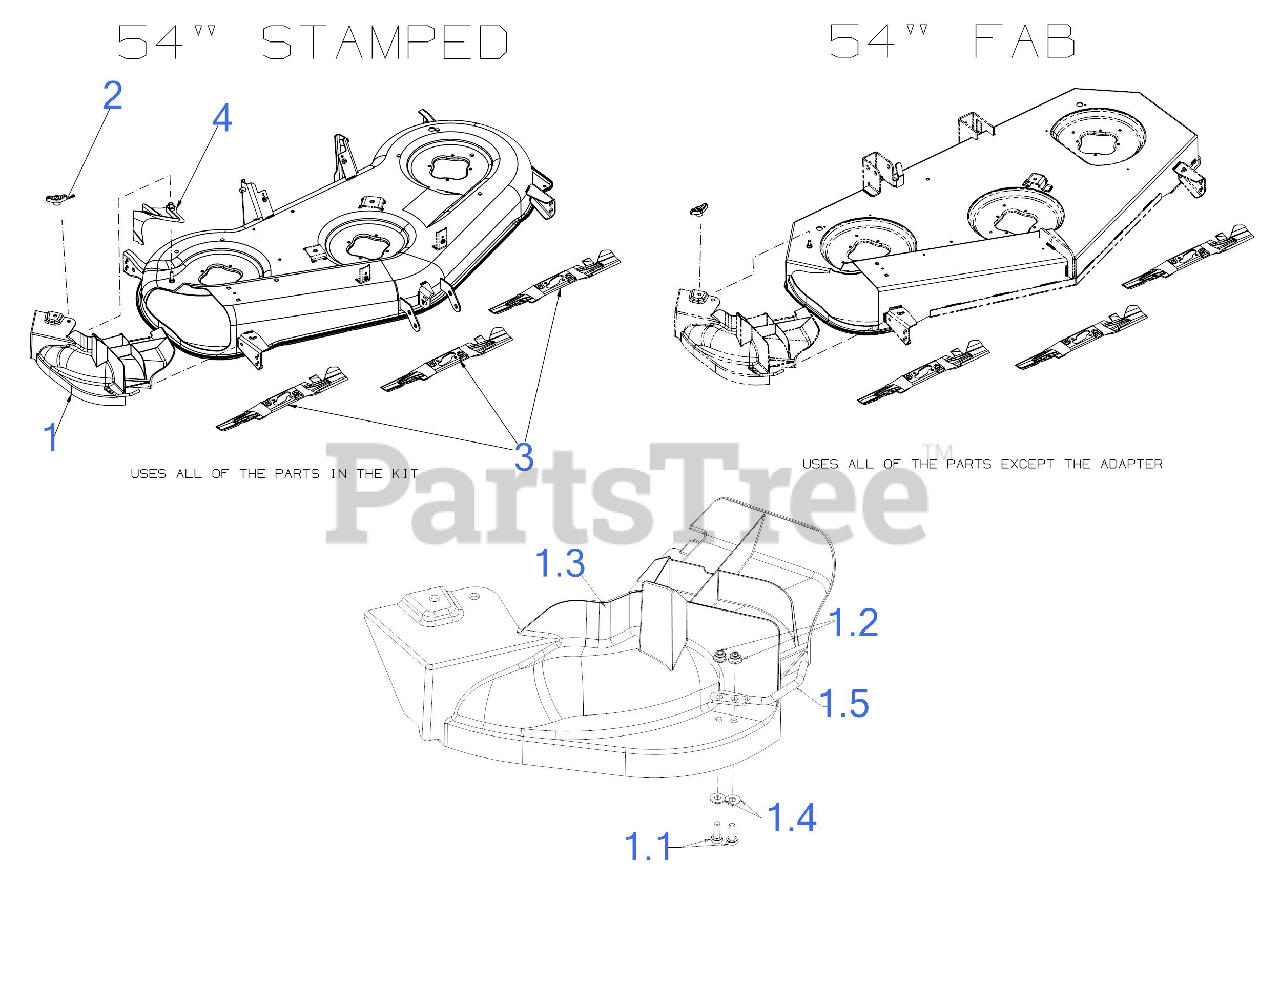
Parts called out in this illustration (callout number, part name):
1	MULCH PLUG ASSEMBLY
1.1	SCREW 1/4-20X.75 GR5
1.2	FLANGE LOCK NUT
1.3	MULCH PLUG
1.4	WASHER
1.5	MULCH PLUG MOUTING ROD
2	WING KNOB 5/16-18
3	54" EXTREME FASTATTACH BLADE
4	CHUTE ADAPTER
